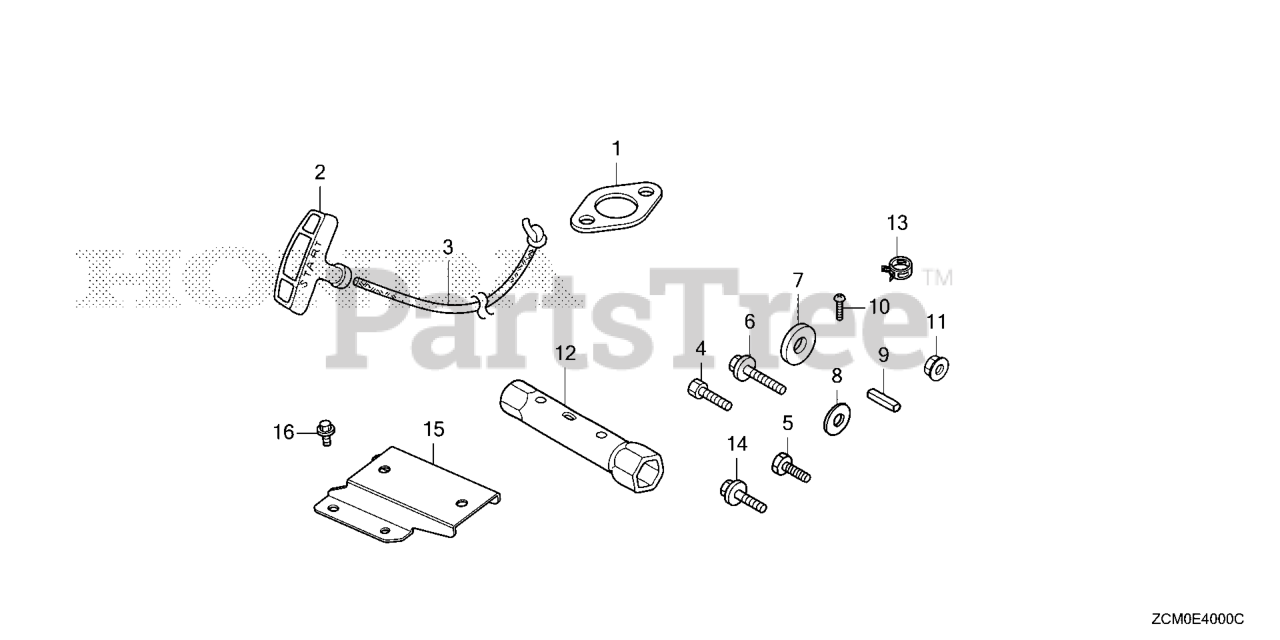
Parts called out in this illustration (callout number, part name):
1	GASKET, EX. PIPE
4	BOLT, HEX. (7/16-20UNF)
9	KEY (6.3X6.3X43)
11	NUT, FLANGE (8MM)
